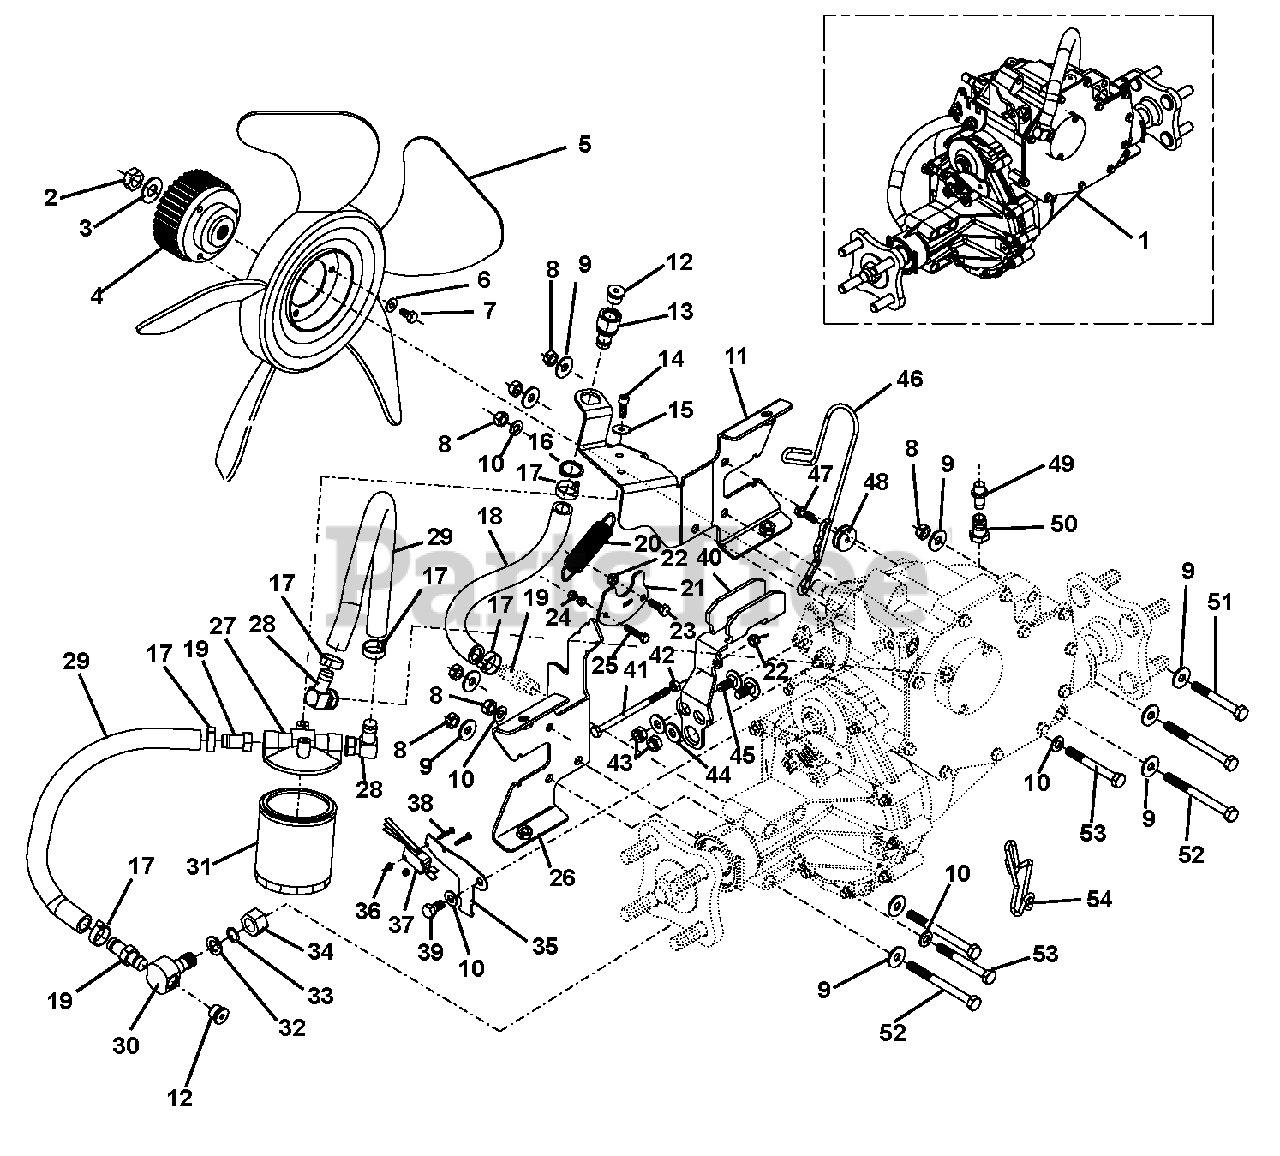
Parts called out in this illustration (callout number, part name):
1	Hydrostat
2	Special Nut
4	Pulley, Hydro
5	Fan
6	Spacer, 1.03 x 1.38 x .184
7	Bolt, Hex D933 M6 x 12
8	Nut, Hex D934 M8
9	Washer, M8
10	Washer, 31181 M8
12	Plug, Steel (with Seal)
13	Support, Tube
14	Screw, UNC 1/4" x 5/8"
15	Washer, M6
16	Circlip, D471 20 1,20
17	Hose Clamp
20	Tension Spring 2,0/17,5 x 87
22	Nut, Lock D985 M6
23	Bolt, Hex D933 M6 x 18
24	Nut, Lock
25	Bolt, Hex D933 M5 x 25
27	Filter Case
30	Connection, Threaded
32	Supporting Ring
34	Nut, Hex
36	Nut, Lock D985 M3
37	Switch
38	Screw, Flat Head D85A M3 x 18
39	Bolt, Hex UNF 5/16" x 5/8"
40	Lever, Forward
41	Bolt, Hex D931 M6 x 100
42	Nut, Hex D934 M6
43	Nut, Lock D985 M8
44	Washer, BN737 8,4 x 20 x 2
45	Screw, Truss Head D603 M8 x 20
46	Spring Clip
47	Screw, DIN7500/D M5 x 20
49	Breather
50	Fitting
51	Bolt, Hex D931 M8 x 65
52	Bolt, Hex D931 M8 x 90
53	Bolt, Hex D931 M8 x 70
54	Spring Clip
